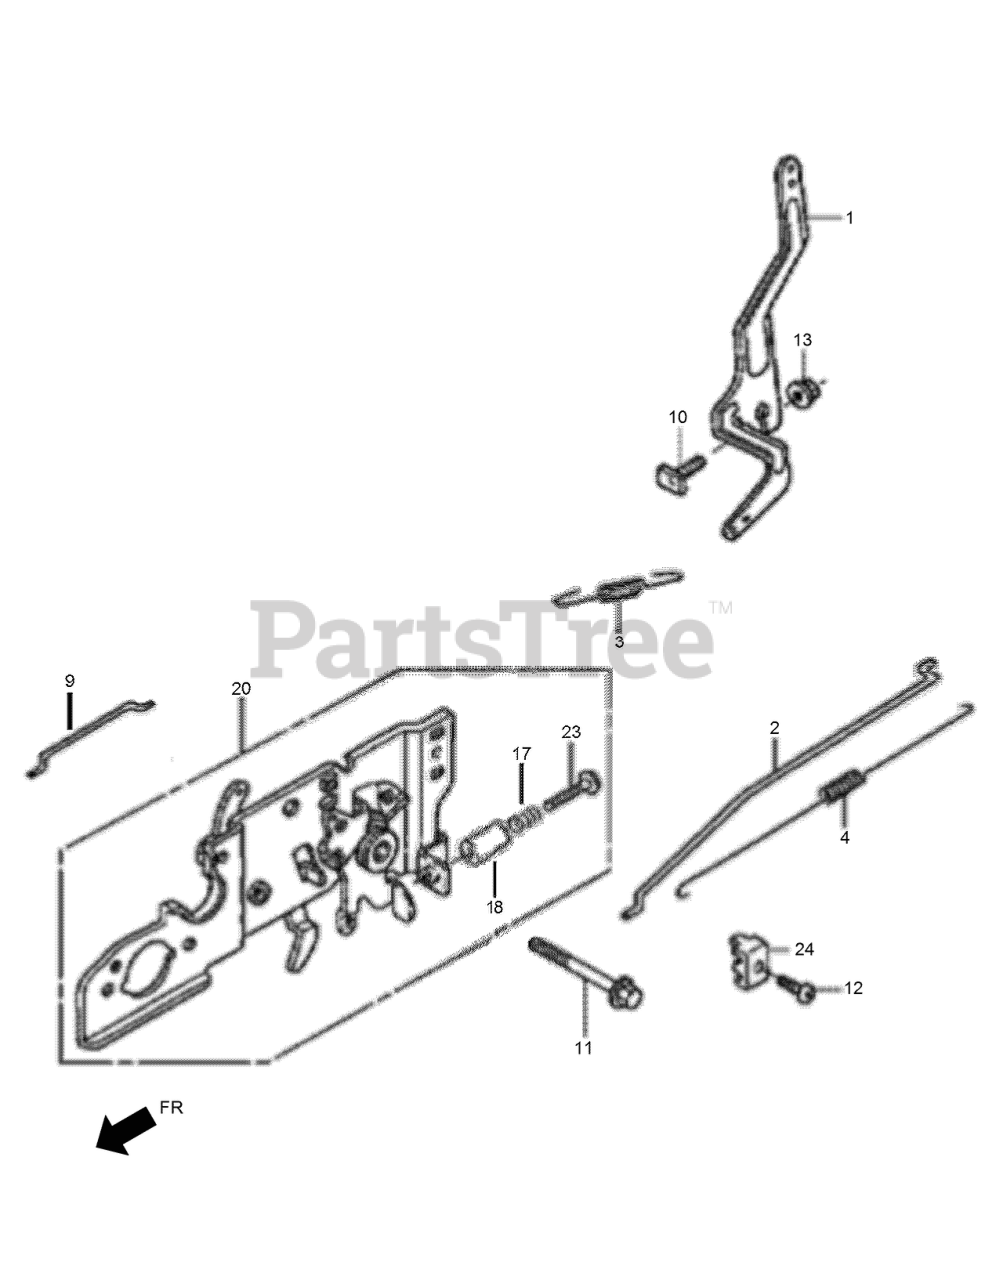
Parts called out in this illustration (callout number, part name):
1	ARM-GOVERNOR
2	ROD-GOVERNOR
3	SPRING-GOVERNOR
4	SPRING-THROTTLE RETURN
9	ROD-CHOKE
10	BOLT-GOVERNOR ARM
11	BOLT-FLANGE-6X45
12	SCREW-PAN-5X16
13	NUT-FLANGE-6MM
17	SPRING-CONTROL ADJUSTING
18	COLLAR-STOPPER
20	CONTROL BASE ASM
23	SCREW-RECESSED-5X28
24	HOLDER-CABLE
